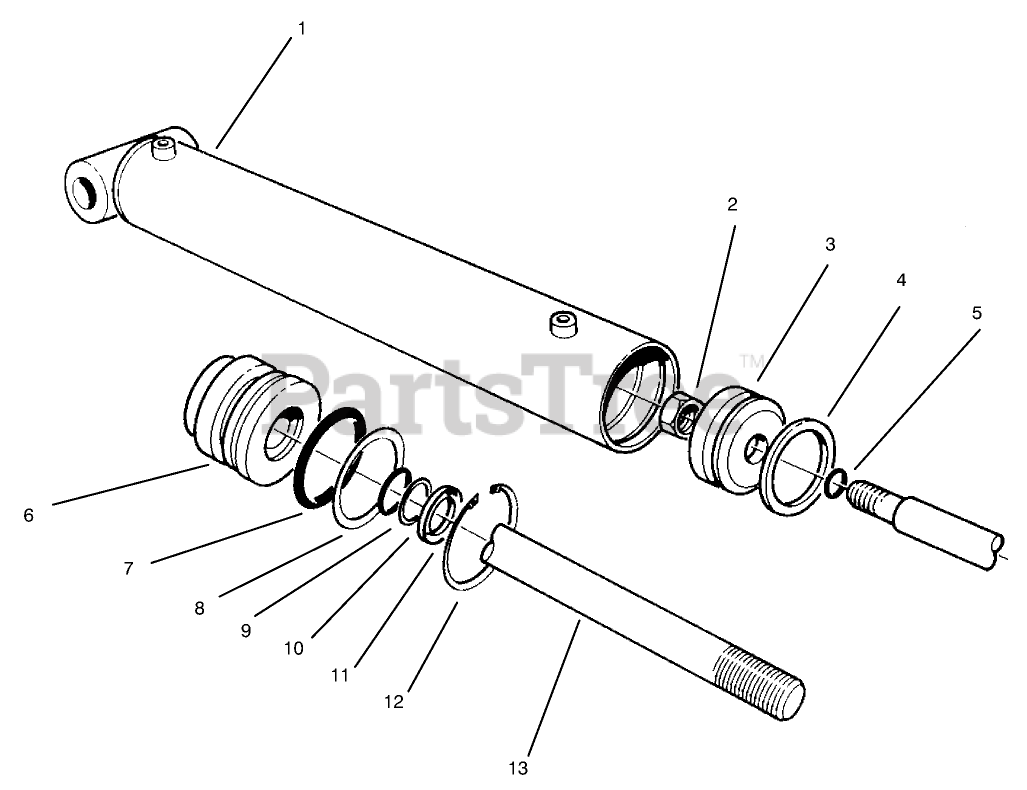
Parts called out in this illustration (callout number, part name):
1	Barrel
2	LOCKNUT
3	PISTON
5	"O" Ring
7	"O" Ring
9	"O" Ring
12	RING-RETAINING
13	SHAFT
